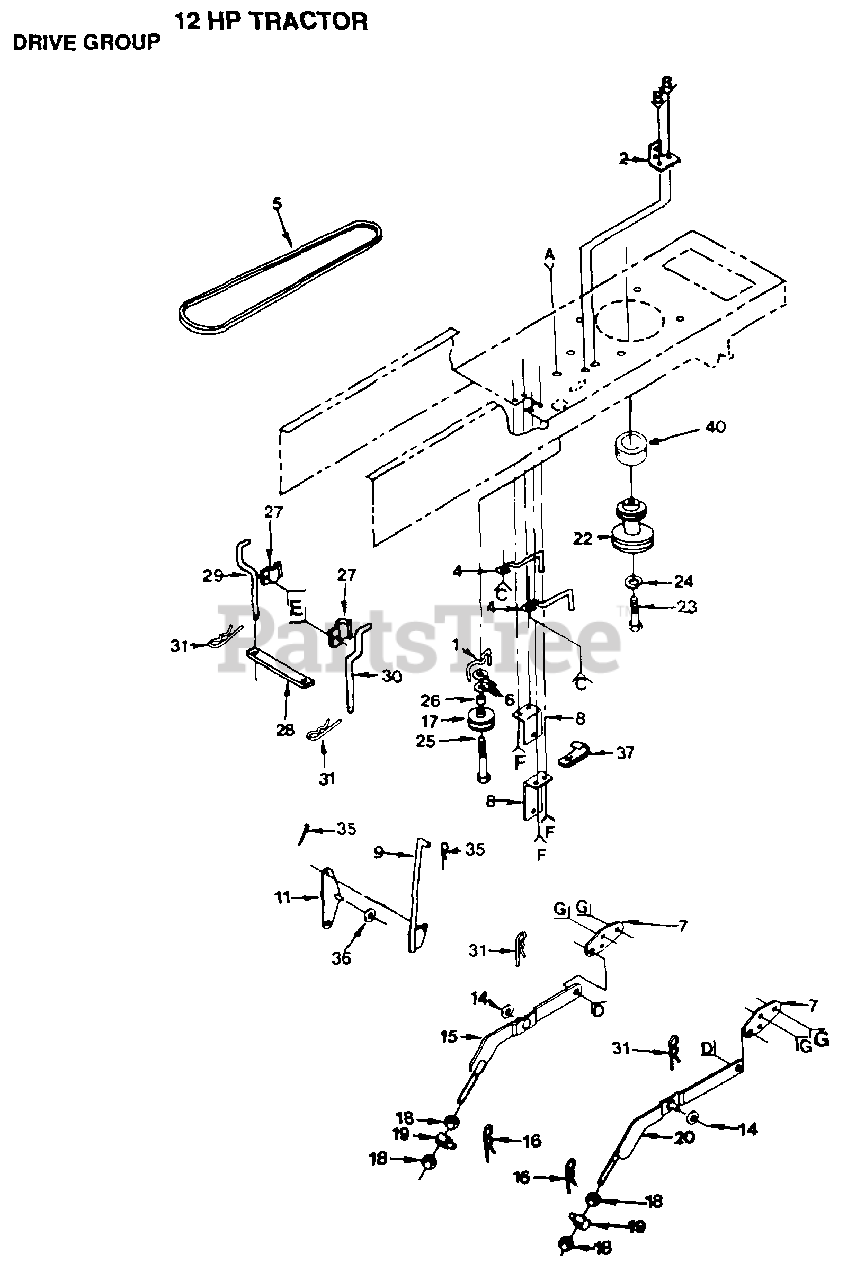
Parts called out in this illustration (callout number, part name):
2	BRACKET LT
4	"KEEPER,BLT ENG LT"
5	BELT-V.90.0.GD.DR
6	WASHER
7	"BRACKET, SUSPE T"
8	"BRKT,BELLCRAN T"
9	ROD ASSEM YT
11	"T, BELLCRANK"
15	LH SUSP ARM ASM
16	SPRING H
18	NUT
20	RH SUSP ARM ASM
23	BOLT RER
24	LOCKWASHER
25	BOLT
26	SPACER T
27	CLAMP LT
28	STRAP LOCATOR
29	KEEPER BELT LH
30	KEEPER BELTRH
31	SPRING.RETAINER
35	COTTER PIN
36	WASHER
37	INSUL CLIP T
40	SPACER T
